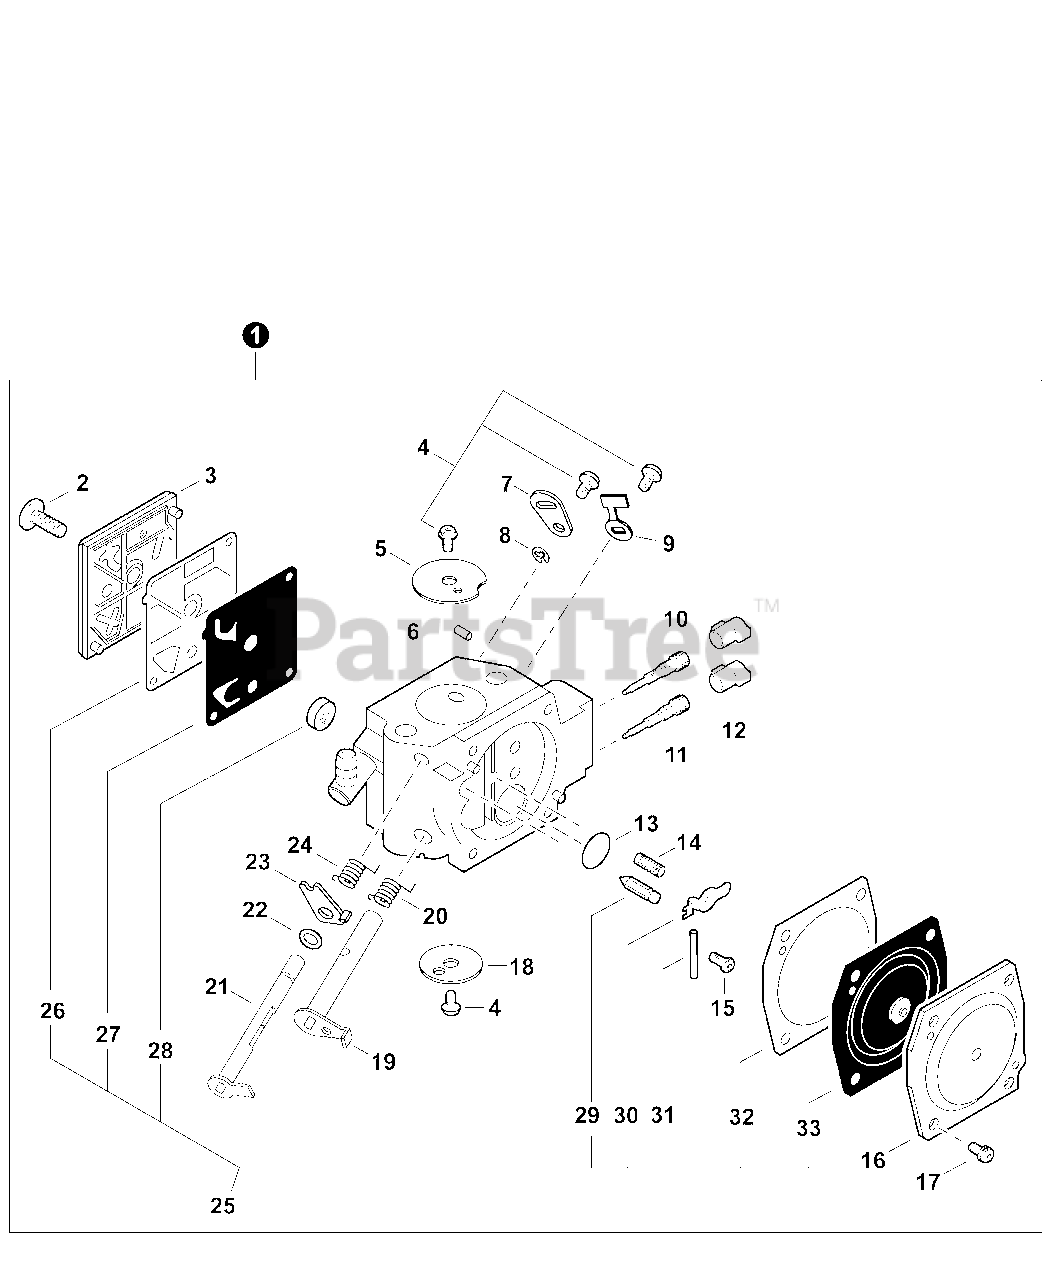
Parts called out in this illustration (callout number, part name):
1	CARBURETOR HDA-324
3	COVER, FUEL PUMP
5	VALVE, CHOKE
6	PLUG, FRICTION
7	LEVER, CHOKE
9	STOP, THROTTLE
10	NEEDLE, HIGH SPEED
11	NEEDLE, MIXTURE
12	CAP, LIMITER
13	PLUG, WELCH
15	SCREW, METERING LEVER PIN
16	COVER, METERING DIAPHRAGM
18	VALVE, THROTTLE
19	SHAFT, THROTTLE
20	SPRING, THROTTLE RETURN
21	SHAFT, CHOKE
23	LEVER, FAST IDLE
24	SPRING, CHOKE RETURN
25	REPAIR KIT
26	GASKET, FUEL PUMP
27	DIAPHRAGM, FUEL PUMP
28	SCREEN, FUEL INLET
29	VALVE, INLET NEEDLE
30	LEVER, METERING
31	PIN, METERING LEVER
32	GASKET, METERING DIAPHRAGM
33	DIAPHRAGM, METERING
